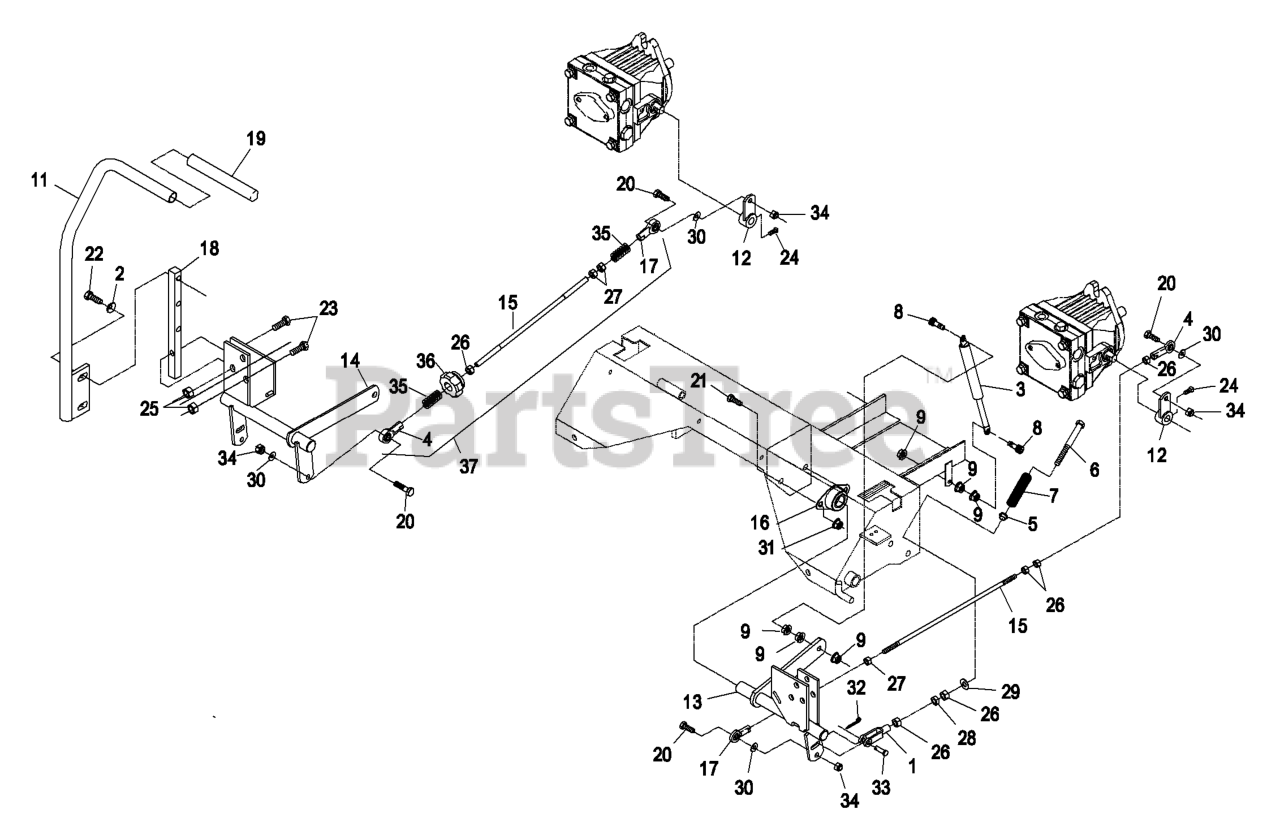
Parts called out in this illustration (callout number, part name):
1	YOKE-ADJUSTABLE
2	WASHER-BELLEVILLE
4	BALLJOINT-RH
5	BUSHING-FLANGED
6	BOLT-RETURN, NEUTRAL
7	SPRING-RETURN, NEUTRAL
8	SCREW-HH
11	RH LEVER ASM
12	ARM-CONTROL, PUMP
14	CONTROL-MOTION, RH
15	LINK-ROD, TRACKING
16	BEARING-FLANGE, SIDE
17	BALLJOINT-LH
18	ARM-SHAFT, CONTROL
19	GRIP-CONTROL, MOTION
20	SCREW-HH
21	SCREW-HH
22	SCREW-HH
23	SCREW-HH
24	SCREW-SET
25	NUT-LOCK, NI
26	NUT-HEX
28	NUT-JAM
29	WASHER-FLAT
30	WASHER-FLAT
31	NUT-HHF, WHIZ
32	PIN-COTTER
33	PIN-CLEVIS
34	NUT-LOCK, NI
35	SPRING-COMPRESSION
36	KNOB-TRACKING
